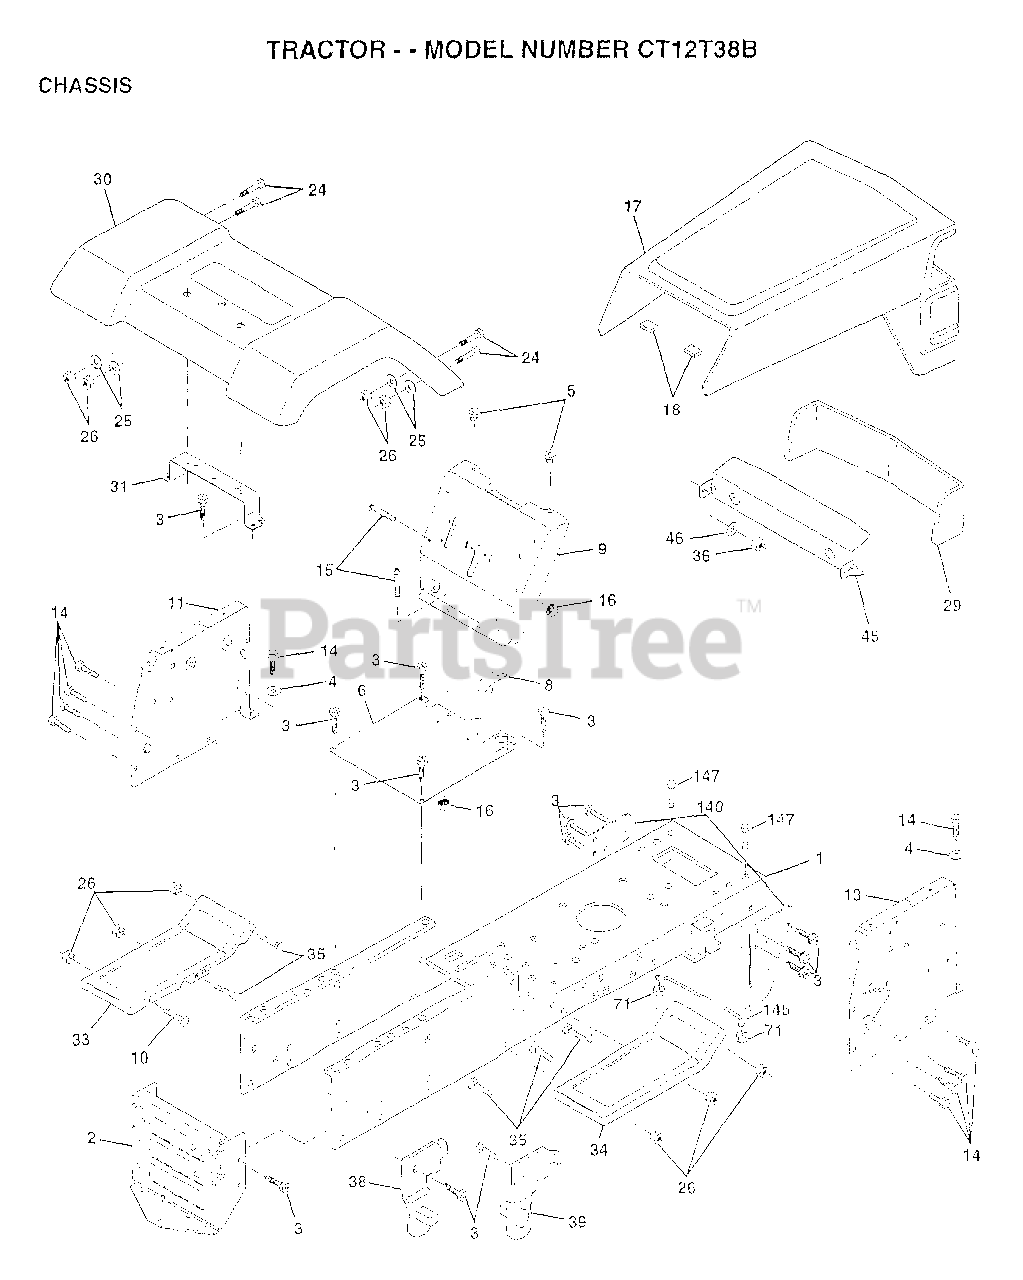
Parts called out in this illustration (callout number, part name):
1	CHASSIS ASM
3	SCREW
4	WASHER
5	BUMPER-HOOD/DASH
6	SADDLE-SILKSCREEN
8	CLIP.RETAINER
9	DASH SILKSCR
11	"PANEL-DASH,LH"
14	SCREW LT
15	SCREW
17	HOOD/GRILL ASM
24	BOLT
25	WASHER
26	NUT
29	LENS SERVICE KIT
30	FENDER
31	BRKT FENDER
33	FOOTREST LH
34	FOOTREST RH
35	BOLT
36	PAL NUT LT
38	BRACKET ASM LH
39	BRACKET ASM RH
46	RETAINER
140	BRKT SUSPENSION
145	"ROD POVOT,CHASSIS"
147	BOLT LT
